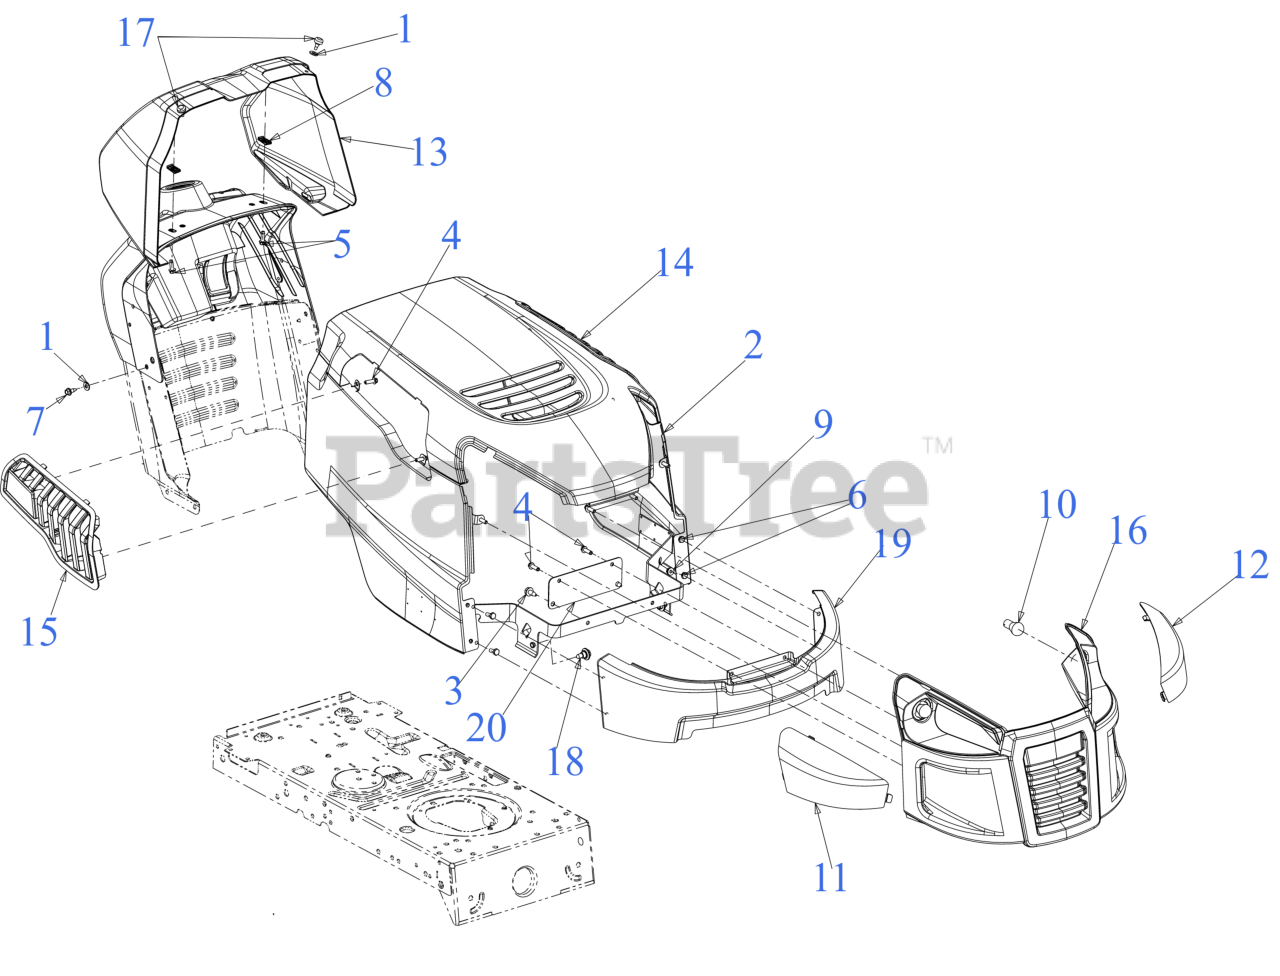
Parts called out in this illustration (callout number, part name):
1	FLAT WASHER 1/4 SAE ZINC
3	SCREW 5/16-18 x .750
4	SCREW 1/4 x .750
5	SCREW 1/4-20 x .750
6	SCREW 1/4-20 x .620 GR5
7	SCREW 1/4-20X.625
8	SPEED NUT
9	FLANGE LOCK NUT
10	MINIATURE LAMP-12V #1156
11	CRAFTSMAN LENS (RH)
12	CRAFTSMAN LENS (LH)
13	DASH COLLER
14	HOOD SCOOP (LH)
15	HOOD SCOOP (RH)
16	GRILLE(S STYLE) W/O LABEL
17	BUMPER, .62 DIA x .3
18	SHOULDER SCREW .43X.29X5/16-18 TT
20	LOWER GRILLE BRACKET
